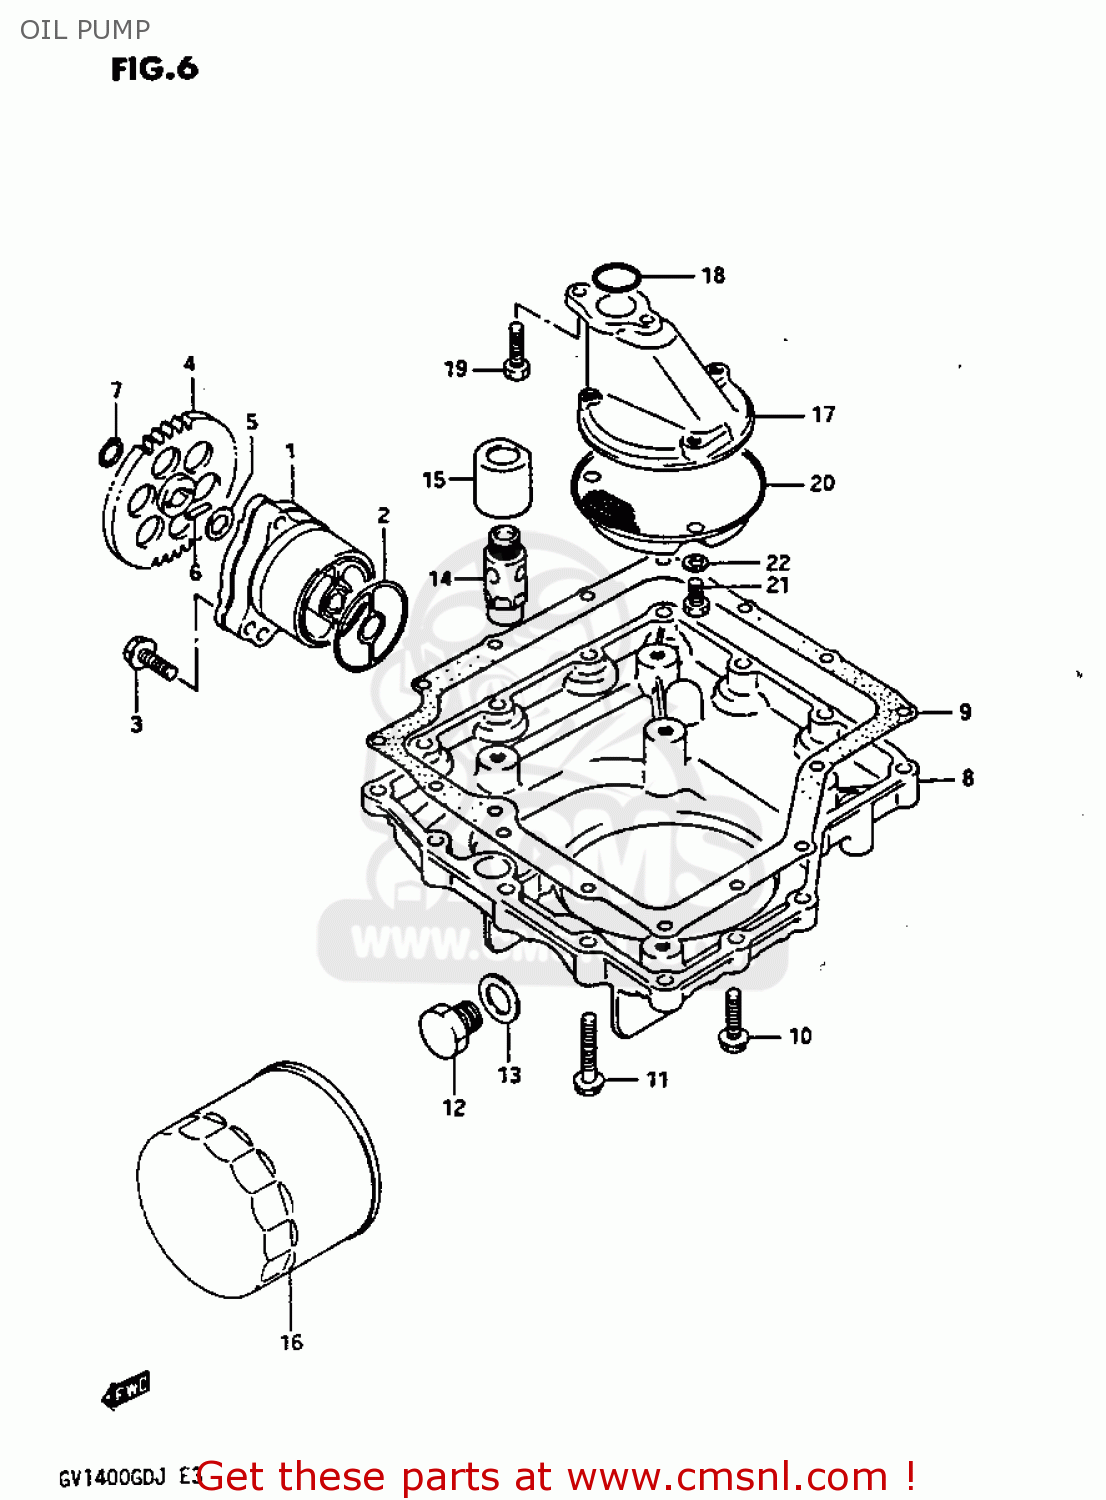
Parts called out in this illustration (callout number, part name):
1	PUMP ASSEMBLY,ENGINE OIL
2	O RING,OIL PUMP
3	BOLT
4	GEAR,OIL PUMP DRIVEN
5	SHIM
6	PIN(4X15.8)
7	CIRCLIP
8	PAN,OIL
9	GASKET,OIL PAN
10	BOLT 6X25
11	BOLT
12	PLUG
13	GASKET(14X19.2X2) (NAS)
14	VALVE ASSY,OIL RELIEF
15	GUIDE, VALVE
16	FILTER ASSY,ENGINE OIL
17	PROTECTOR,OIL STRAINER
18	O RING(D:3.2,ID:17.8)
19	BOLT 6X20
20	STRAINER,ENGINE OIL
21	BOLT
22	WASHER,LOCK
